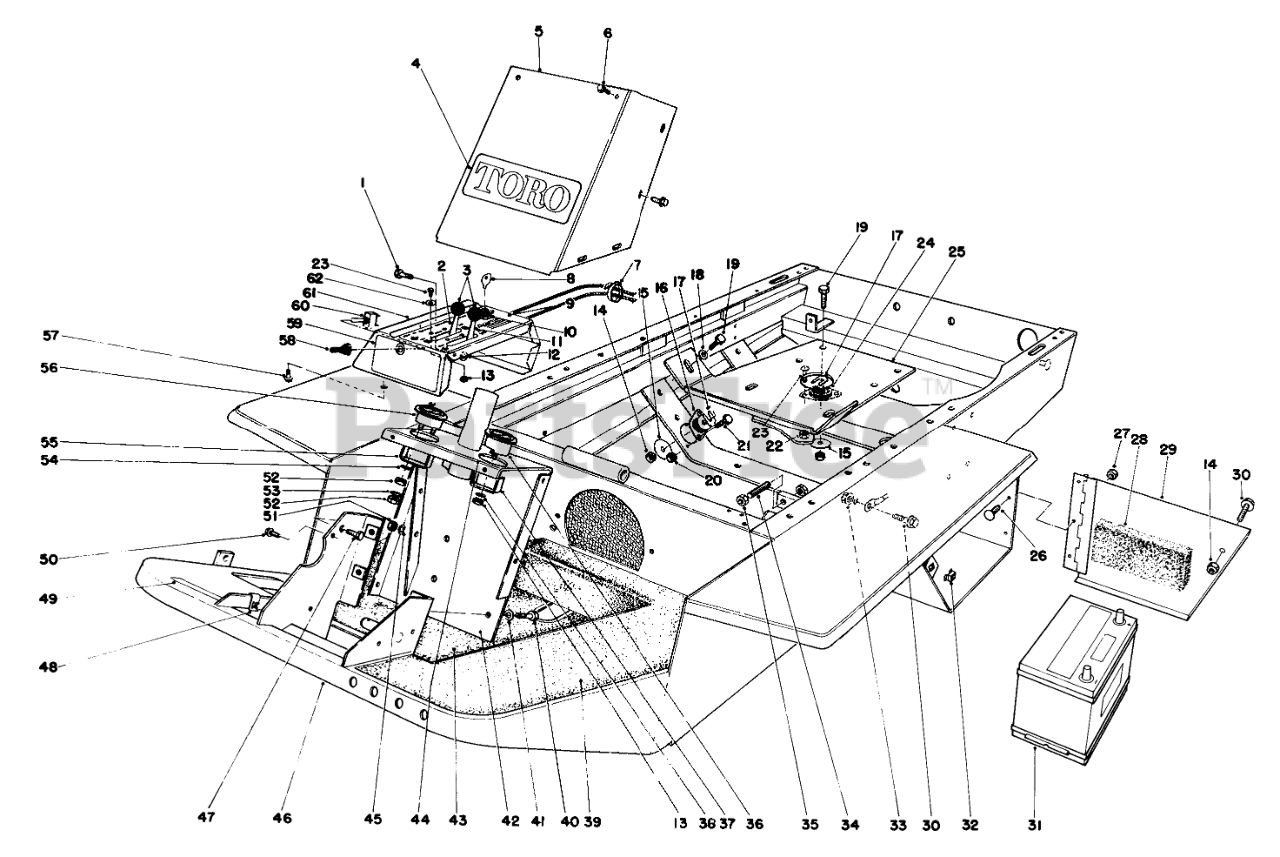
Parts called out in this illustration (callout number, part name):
1	SCREW-HH
2	CHOKE CONTROL
4	Decal
5	Tower Cover
6	SCREW-HHFTF
7	TIE-CABLE
8	Key
9	Decal-Instrument Panel
10	SWITCH
11	THROTTLE CONTROL
12	WASHER-FLAT
13	NUT-HEX
14	NUT-LOCK, NI
15	WASHER
16	ENGINE RUBBER MT
17	SHIM-AXLE
18	WASHER-FLAT
19	SCREW-HH
20	NUT-LOCK, NI
21	SCREW-HH
22	NUT-LOCK, NI
23	10-24 X 5/8 PAN HD MS
24	RUBBER MOUNT
25	Base-Engine
26	SCREW-HSBH
27	NUT-LOCK, NI
28	BATT BOX FOAM
29	Battery Cover
30	SCREW-HHF
31	Battery Assy.
32	RETAINER NUT
33	NUT-HHF, WHIZ
34	STOP PIN PP
35	NUT-JAM
36	HOUR METER
37	BRACKET F/W
38	WASHER-LOCK, INT
39	NON SKID (TUNNEL)
40	SCREW-HH
41	WASHER-LOCK
42	Steering Post
43	NON-SKID-FLOOR
44	INSTRUCTION DECAL
45	WASHER-LOCK
46	FRAME WA
47	SCREW-HH
48	SPEED NUT
49	DECAL-PEDAL, TRACTION
50	SCREW-HWH
51	NUT-HEX
52	NUT-HEX
53	WASHER-LOCK
54	WASHER-FLAT
55	MTG CLAMP F/W GUAGE
56	AMMETER GAUGE ASSY
57	SCREW-THD FRM,HWH
58	BOOT-SWITCH
59	BY-PASS DECAL
60	SWITCH & BOOT ASM
61	Instrument Panel
62	WASHER-LOCK
